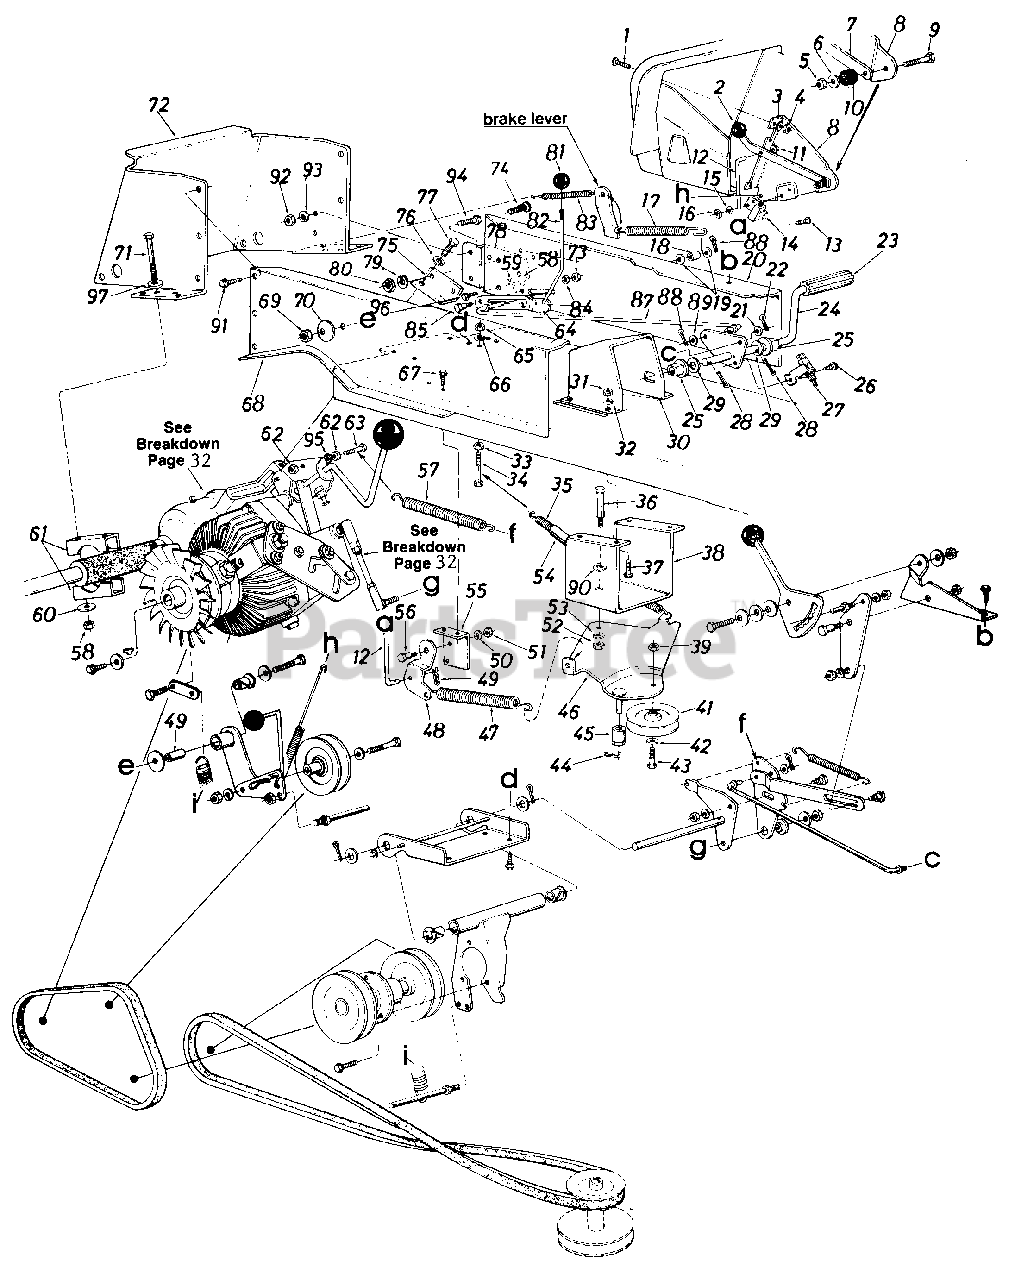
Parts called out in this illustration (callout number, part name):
1	Truss Mach. Scr. 1/4-20 x 60" Lg
2	Knob-Blade Clutch
4	Hex Sems Nut 1/4-20 Thd.
5	Hex Cent. L-Nut 1/4-20 Thd.
6	Fl-Wash. 1/4" I.D. x .75n O.D.
7	PTO Lever
8	Deck Clutch Control Brkt.
9	Hex Bolt 1/4-20 x .75" Lg.
10	Rubber Wash. .33" I.D. x 87n O.D.
11	Push Cap 1/4" Rod
12	Deck Control Rod
13	Truss Mach. Scr. #10-24 x .50" Lg.
14	Safety Switch
15	Ext. L-Wash. #10 Scr.
16	Hex Nut #10-24 Thd.
17	Extension Spring .75" O.D. x 5.56" Lg.
18	Spacer.375" I.D. x .625" O.D. x .445" Lg.
19	Fl-Wash. 385" I.D. x 87" O.D.
20	Side Panel Upper Frame-L.H.
21	Fl-Wash. .385" I.D. x .87" O.D.
22	Cotter Pin 8/32" Dia. x .75"
23	Foot Pad
24	Foot Pedal Brkt. Ass'y.
25	Flange Brg. 630" I.D. x 1.25" O.D.
26	Hex Wash. Hd. S-Tap Scr. 1/4-20 x 50n Lg.
27	Safety Switch
28	Cotter Pin 1/8" Dia. x 1.00"
29	Fl-Wash. .640" I.D. x .24" O.D.
30	Steering Gear Support Ass'y.
31	Fl-Wash. 885" I.D. x .87" O.D.
32	L-Wash. 5116" I.D.
33	Hex Nut 1/4-20 Thd.
34	Hex Bolt 1/4-20 x 2.0" Lg.
35	Extension Spring .50" O.D. x 6 87n Lg.
36	Shld. Bolt 7/16" Dia. x .16"
37	Hex Bolt 5/16-18 x 1.00"
38	Idler Mtg. Brkt.-Deck
39	Hex L-Nut 3/8-16 Thd.
41	"V"-Idler Pulley
42	Fl-Wash. 3/8" I.D.
43	Hex Bolt 3/8-16 x 1.75" Lg.
44	Cotter Pin 5/16" Rod
45	Spacer
46	Idler Brkt. Ass'y.
47	Extension Spring-Deck Control
48	Deck Control Pivot Brkt.
49	Cotter Pin 5/16" Rod
50	L-Wash. 5/16" I.D.
51	Hex Nut 5/16-18 Thd.
52	Hex Nut 5/16-18 Thd.
53	L-Wash. 5/16" I.D.
54	Convoluted Conduit .50" I.D. x4" Lg.
55	Parking Brake Cam Mtg. Brkt.
56	Shld. Bolt 7/16" Dia. x .16"
57	Extension Spring
58	Hex Nut 3/8-16 Thd.
59	L-Wash. 3/8" I.D.
60	Bell-Wash .39" I.D. x 1.13"
61	Rear Axle Brkt.
62	Hex Nut 5/16-24 Thd.
63	Hex Scr. 5/16-24 x 1.5"
64	Parking Brake Cam
65	Hex Nut 1/4-20 Thd.
66	L-Wash. 1/4" I.D.
67	Hex Wash. Hd. S-Tap Scr. 1/4-20 x .50" Lg.
68	Side Panel Upper Frame-R.H>
69	Hex Nut 3/8-24 Thd.
70	Fl-Wash. .39" I.D. x 1.5" O.D.
71	Hex Bolt 3/8-16 x 3.50" Lg.
72	Hitch Plate
73	Hex Nut 3/8-16 Thd.
74	Rd. Hd. Ribbed Neck Bolt 3/8-24 x 1.0" Lg.
75	Mounting Brkt. Transaxle
76	L-Wash. 3/8" I.D.
77	Hex Bolt 3/8-16 x l.OO" Lg. (Grade 5)
78	Reinforcement Plate-Frame
79	L-Wash. 3/8" I.D.
80	Hex Nut 3/8-24 Thd.
81	Gear Shift Knob
82	Parking Brake Link
83	Extension Spring .38" O.D. x 3.18" Lg.
84	Hex Nut 3/8-16 Thd.
85	Shld. Bolt .500" Dia. x .170
87	Rod-Brake .38" Dia. x 19.3" Lg.
88	Cotter Pin 3/32" Dia. x .75"
89	Fl-Wash. .385" I.D. x .87"
90	Wave Wash.
91	Hex AB-Tap Scr. 5/16 x .75"
92	Hex Nut 5/16-24 Thd.
93	L-Wash. 5/16" I.D.*
94	Hex Bolt 5/16-24 x .75n Lg.
95	L-Wash. 5/16 I.D.
96	Hex Bolt 3/8-16 x .75" Lg.
97	Fl-Wash. .385"'1.D. x .870" O.D.
